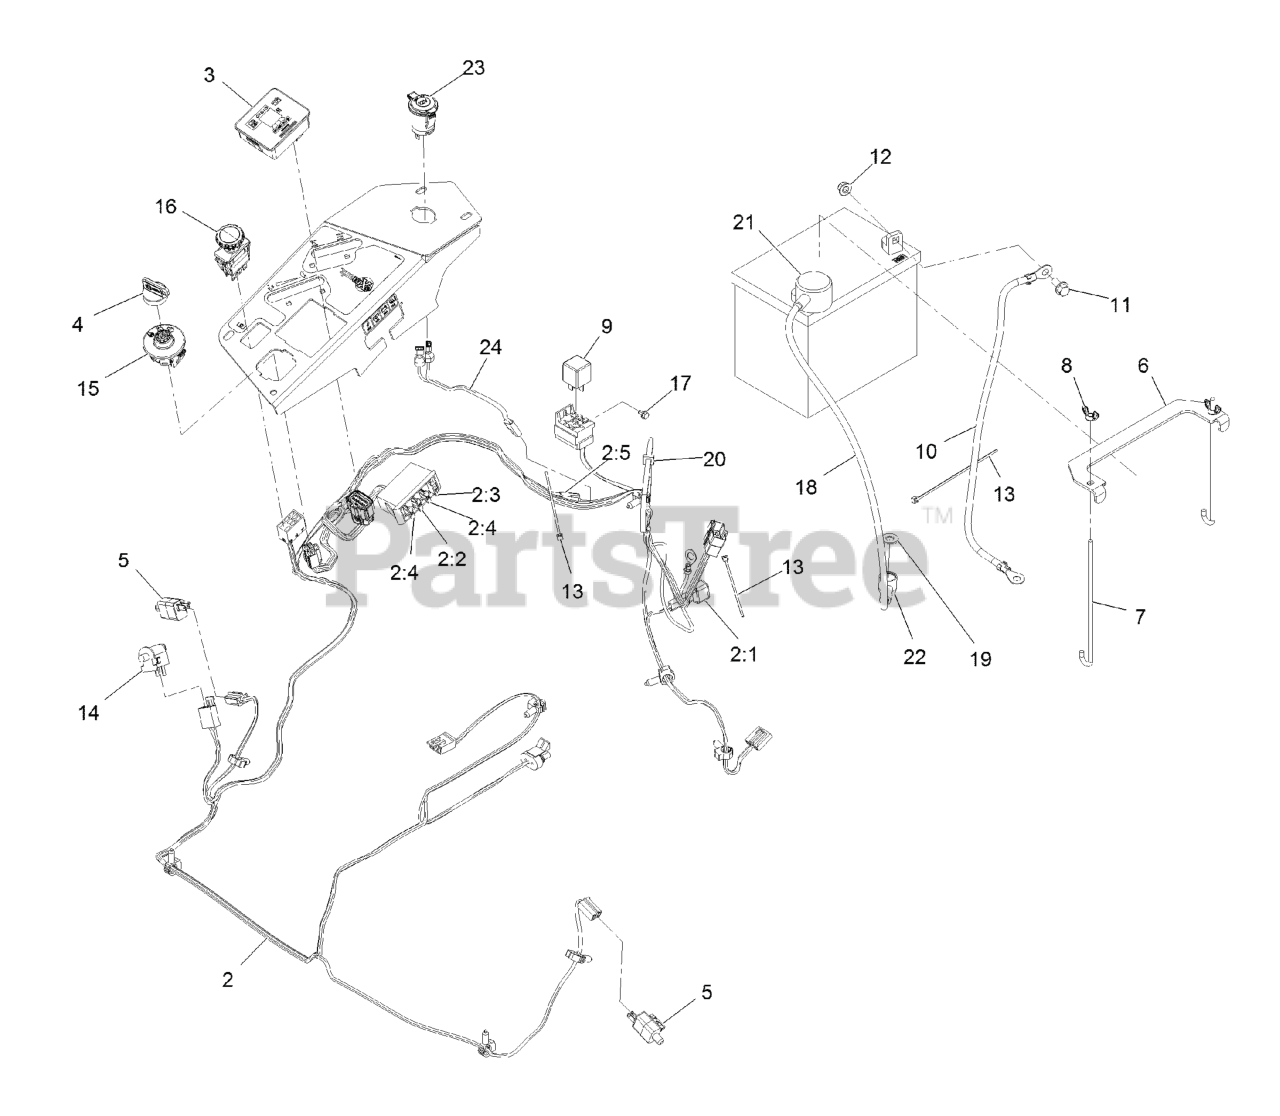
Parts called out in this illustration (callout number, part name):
2	HARNESS-WIRE, MAIN
2:2	FUSE-BLADE, 10 AMP
2:3	FUSE-BLADE, 15 AMP
2:4	FUSE-BLADE, 25 AMP
2:5	CAP-PLUG
3	FUEL/HOUR METER ASM
4	KEYS-IGNITION (SPARE PAIR
4	KEY-IGNITION
6	STRAP-TIE DOWN, BATTERY
7	BOLT-HOLDDOWN
8	WINGNUT
10	CABLE-BATTERY, NEGATIVE
11	SCREW-HHF
12	NUT-HF, NI
13	TIE-CABLE
14	SWITCH-BAIL
15	SWITCH-IGNITION
16	SWITCH-PTO, 10 AMP
17	SCREW-HWH
18	CABLE-BATTERY, POSITIVE
19	WASHER-FLAT
20	TIE-PLASTIC
21	INSULATOR-BATTERY
22	INSULATOR-SOLENOID
23	PORT-POWER, 12V
24	HARNESS, RECEPTACLE 12V
